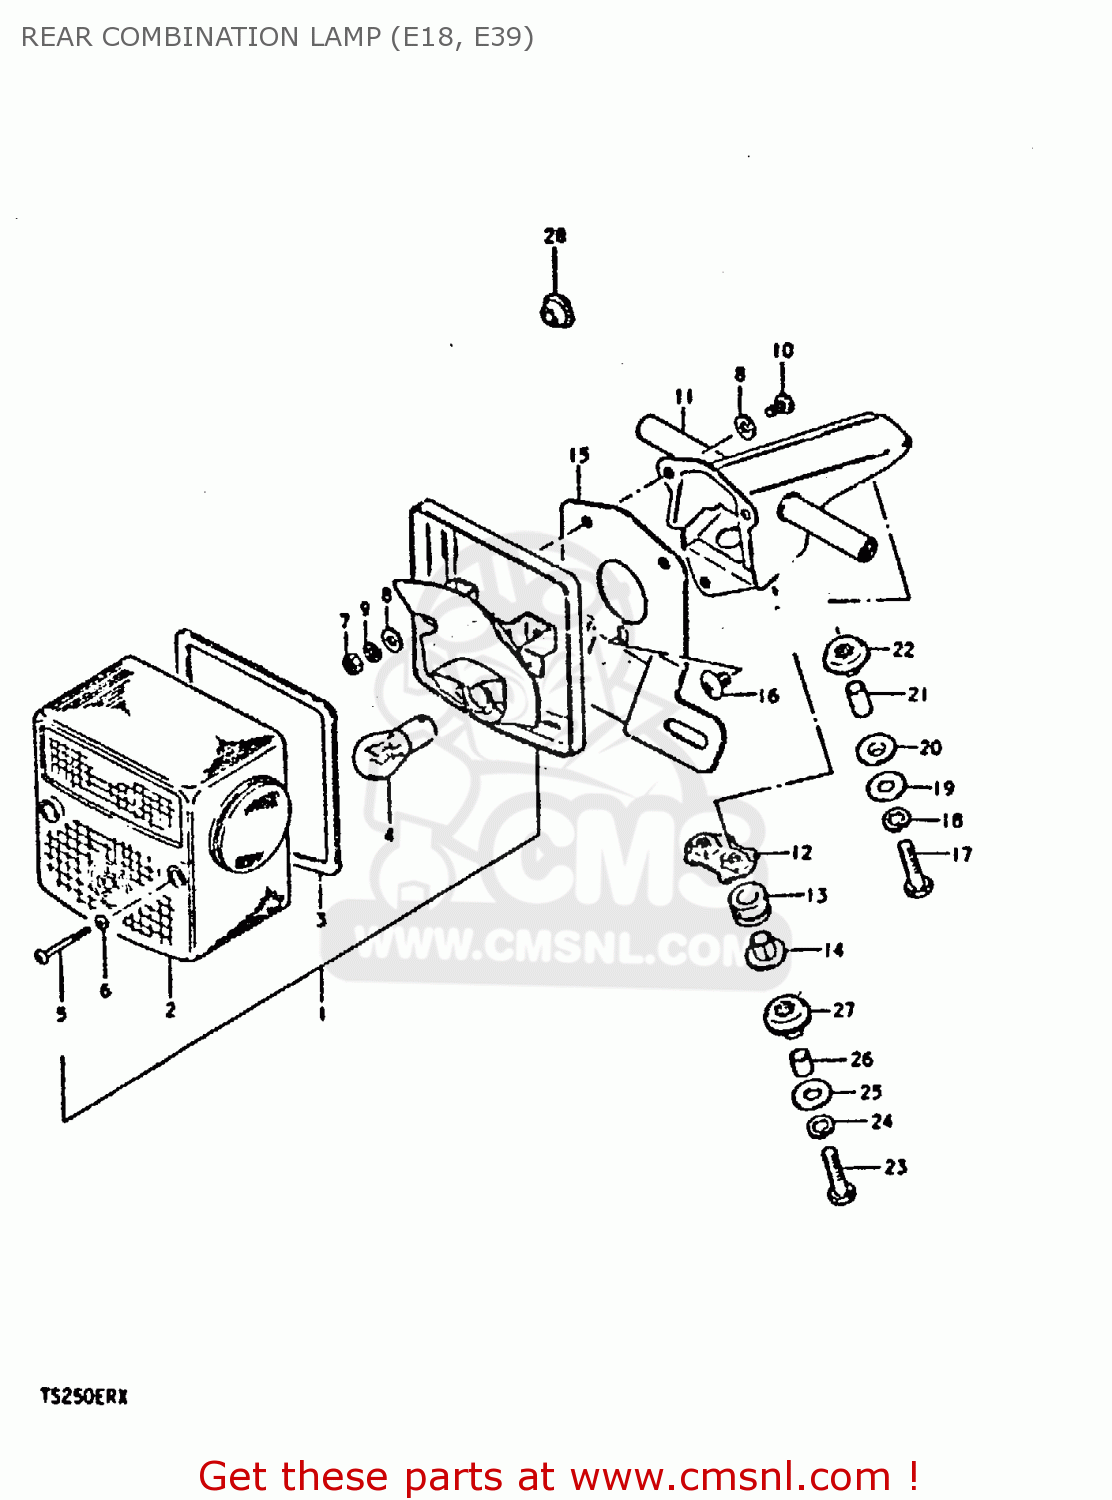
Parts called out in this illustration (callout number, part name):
1	LAMP UNIT, REAR COMBINATION
2	LENS
3	GASKET (NAS)
4	BULB (6V,21/5W)
5	SCREW (4X55)
6	GASKET (NAS)
7	NUT
8	WASHER
9	LOCK WASHER
10	SCREW
11	BRACKET ASSY
12	PLATE
13	CUSHION
14	SPACER
15	PLATE, LICENSE
16	SCREW, PLATE
17	BOLT
18	LOCK WASHER
19	WASHER (6.5X20X1.2)
20	CUSHION
21	SPACER
22	CUSHION
23	BOLT
24	LOCK WASHER
25	WASHER (6.5X20X1.2)
26	SPACER
27	CUSHION
28	GROMMET
